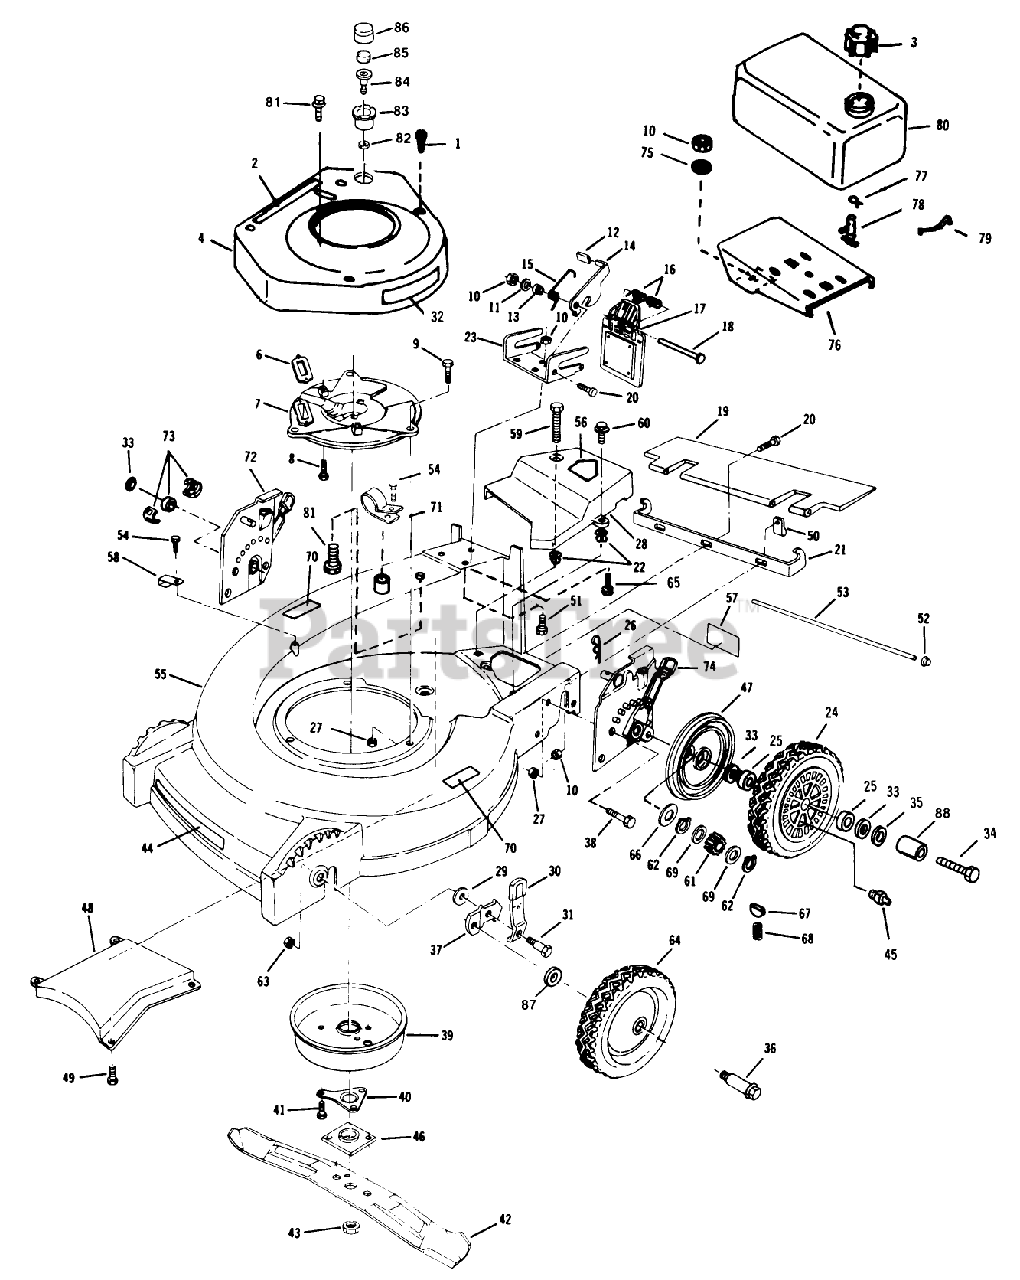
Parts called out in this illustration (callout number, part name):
1	SCREW - SELF TAPPING
3	FUEL CAP & INSERT
7	PLATE F
8	SCREW V
9	SCREW-HH
10	LOCKNUT E
15	SPRING
16	SPRING ASOC
18	ROD (RB&W)
19	T/SHIELD SM&P
26	HAIR PIN
27	NUT-LOCK F
29	WASHER
31	BOLT
33	WASHER
35	SPACER
36	BOLT-SHOULDER
39	MUFFLER COVER F
40	SUPPORT F
41	SCREW
43	NUT-BLADE
45	FITTING LINCOLN
46	PLATE AND COLLAR ASM
48	BAFFLE CHUTE PL
51	SCREW
54	SCREW LAWRENCE
60	SCREW
61	PINION BROCKWAY
62	RET RING
63	LOCKNUT
65	SCREW HEX WASHER
66	THRUST WASHER
67	KEY
68	SPRING
69	SPACER/GR ALGHNY
73	REAR AXLE BEARING
75	WASHER
77	CLAMP - HOSE S
78	VALVE&SCREEN SM
79	SPRING
81	SCREW SEMS SM
83	CUP PRIMER S
84	BASE P'MERBULB S
85	FILTER S
87	WASHER WROUGHT
